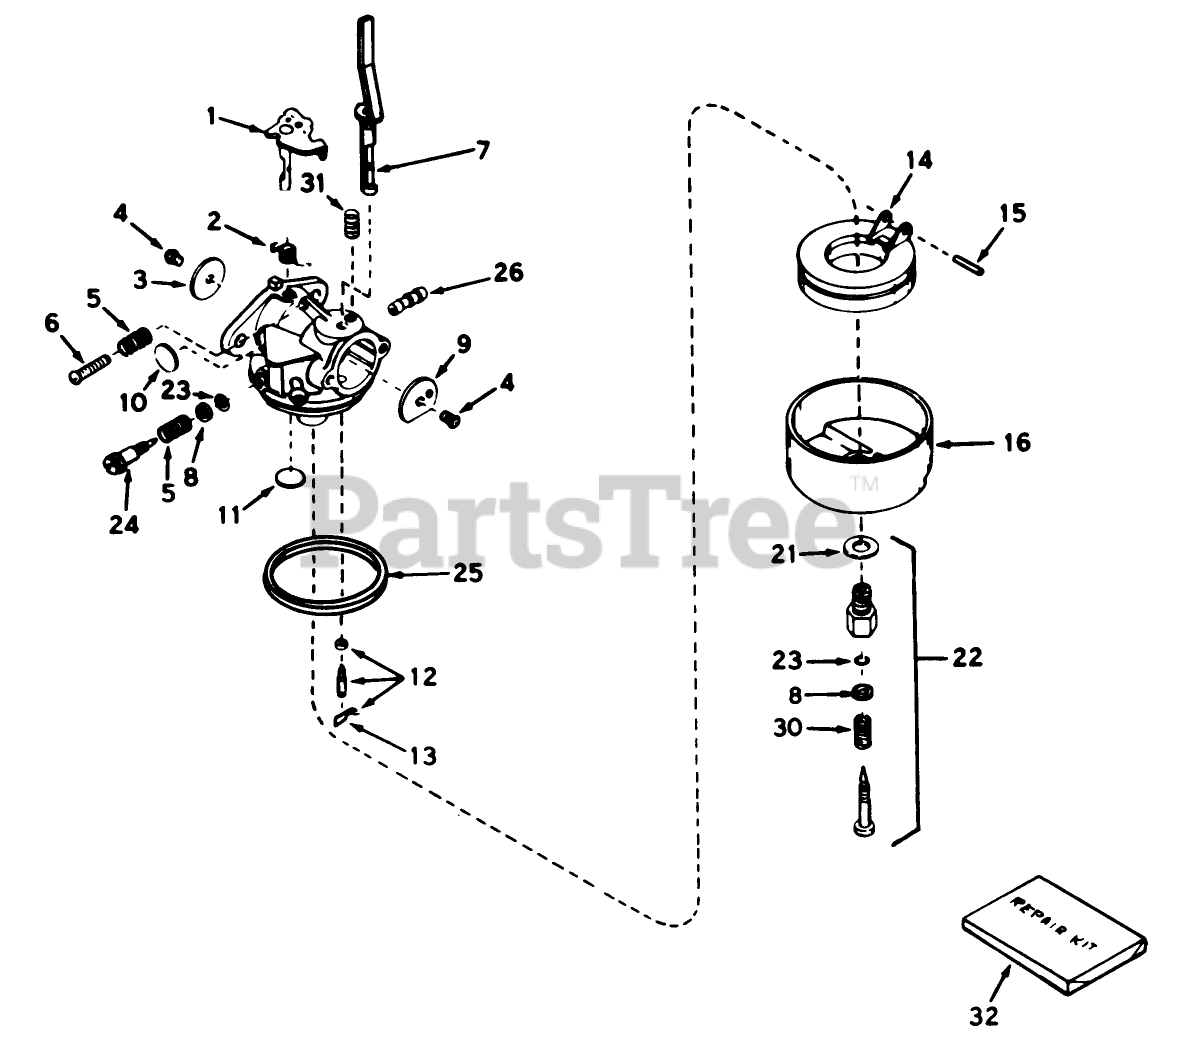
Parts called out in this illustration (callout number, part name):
1	Shaft/Lever-Throttle
2	Spring, Return
3	Shutter-Throttle
4	Screw-Shutter
5	Spring-Tension
6	Screw-Throttle Crack Screw / Idle Speed
7	Shaft Lever Assy., Choke
8	Washer
9	Shutter-choke
10	Plug-Welch, Idle Mixture Well
11	Plug-Welch, Atmospheric Vent
12	Inlet Needle, Seat Clip Assy. (Incl. No. 13)
13	Clip-Spring
14	Float
15	Shaft-Float
16	Bowl-Float (no drain)
21	Washer-Bowl Nut
22	Adjustment Screw Assy., Main (Incl. Nos. 5A, 21 23)
23	ORing
24	Screw, Idle Adj.
25	O Ring-Bowl, Float
26	Fuel Fitting
30	Spring
31	Spring-Positioning, Choke
32	Repair Kit (Incl. items marked *)
